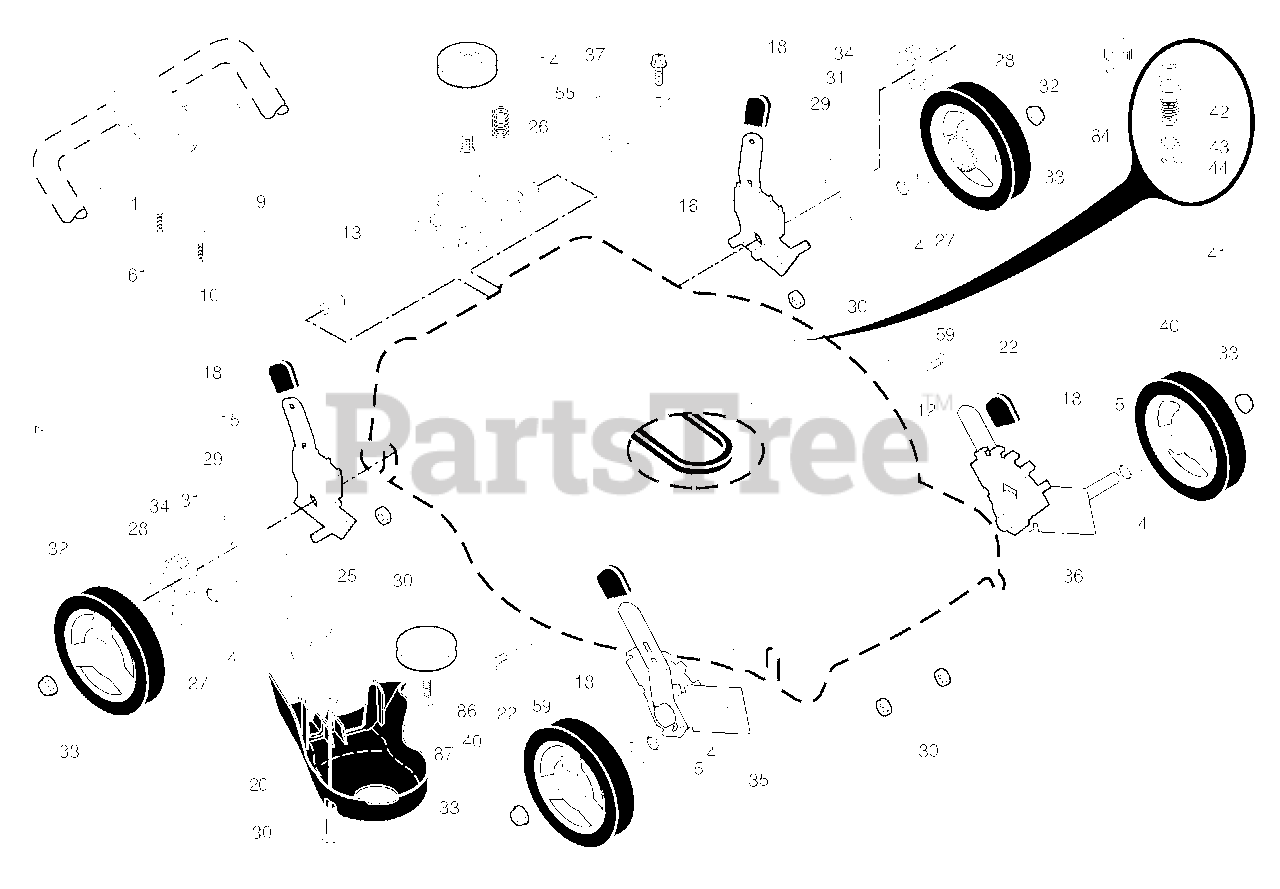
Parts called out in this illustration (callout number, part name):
1	RB CONTRL.AW2.22+RGD.BS.GRY/BK
4	O-RING..070X.487.NEOPRENE
9	CABLE.DRIVE.RWD.WALK.
10	BRACKET.DRIVE.CONTR.GEN2.BLACK
12	BELT.DRIVE.RGD.SS.WALK
13	TRANSMISSION.22+AWD.WALK.MOWER
15	RP ADJ.ASM.9.22+/LF/RR.21/RF
16	RP_ADJUSTER.ASM.9.22+/RF/LR.21
18	SELECTOR KNOB
20	COVER.REAR.DRIVE.22+2013
22	BOLT.5/16HEX.WHS.HD
25	BRACKET.DRIVE.COVER.RGD.
26	BRACKET.TRANS.BELT.KEEPER.BZP
27	WASHER FLUT
28	E-RING 7/16 RE
29	COVER.DUST.WHEEL.INNER.WALK
30	NUT.HEX.FLANGE.1/4
31	PAWL, DRIVE
32	WHEEL.8X1.75.3SPK.RAD3.GREY
33	NUT.HEX.FLANGE.3/8-16.LO(3 2)
34	PINIION.14.TOOTH.RGD
35	ADJUSTER.ASM.9POS.LW.RL/RGD.FR
36	ADJUSTER.ASM.9POS.LW.RR/RGD.
40	WHEEL & TIRES ASSY, FRONT
41	KIT.WASH-OUT.PORT.ZINC.WALK
42	WASHOUT.PORT.ZINC.RGD.22+
43	WASHER.LOCK.INTERNAL.TOOTH
44	LOCKNUT.HEX.WITH.O-RING
55	SPRING.RETURN.AUTO.
59	BRACKET.SUPPORT.22+RWGD.BZP
61	SCREW, PHILLIPS HEAD 10 X 5/8
84	COUPLING.QUICK CONNECT
86	RP PULLEY.AWD.IDLER
